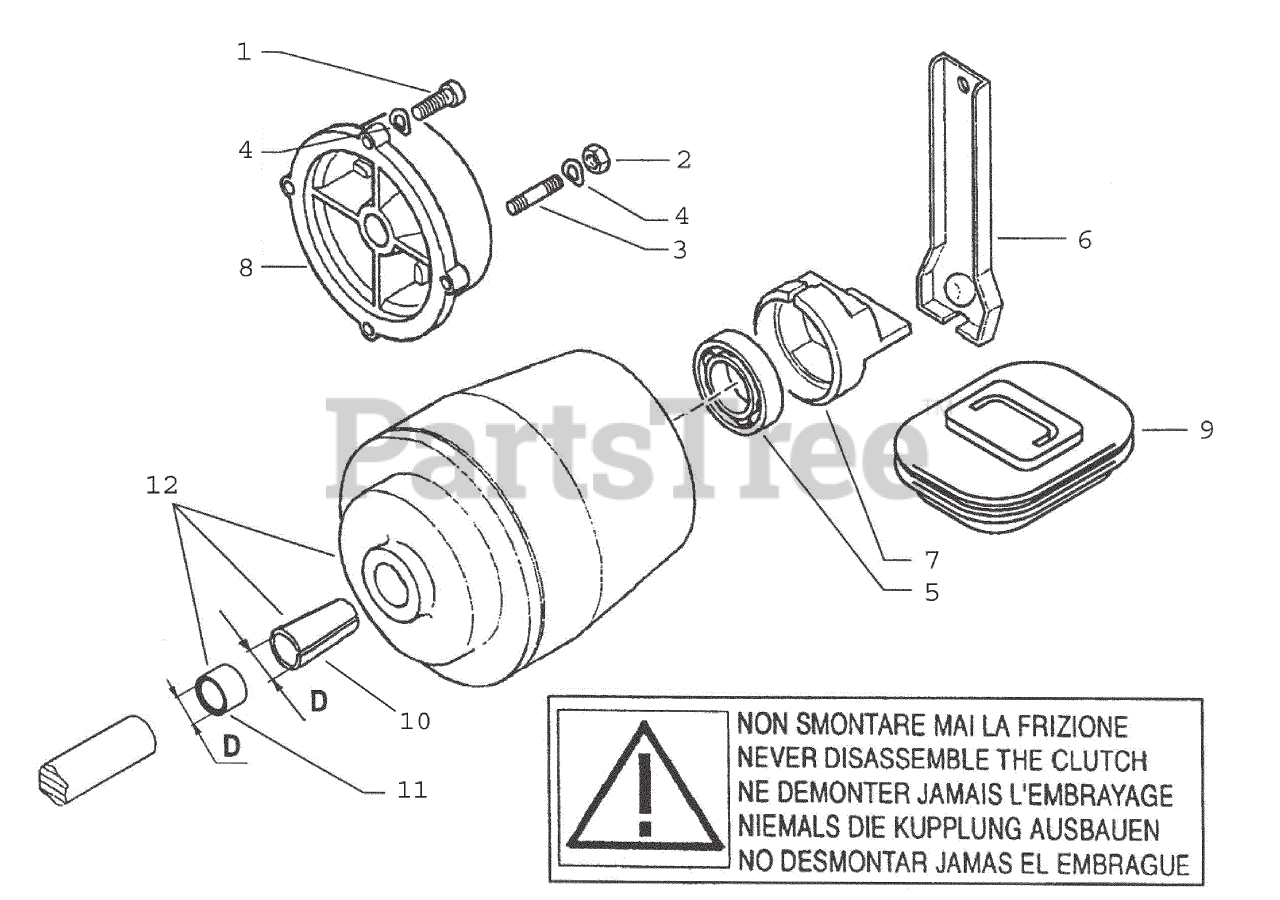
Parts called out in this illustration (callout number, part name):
1	SCREW, 5/16X7/8"
2	NUT, M8
3	STUD, M8X40X14X14
4	WASHER, WAVE
5	BEARING, M17X40X12
6	LEVER, RECOIL START
7	PUSHER CONE
8	FLANGE, 5.5HP HONDA
10	SPACER
11	SPACER
12	CLUTCH, (INCLUDE 5, 7)
